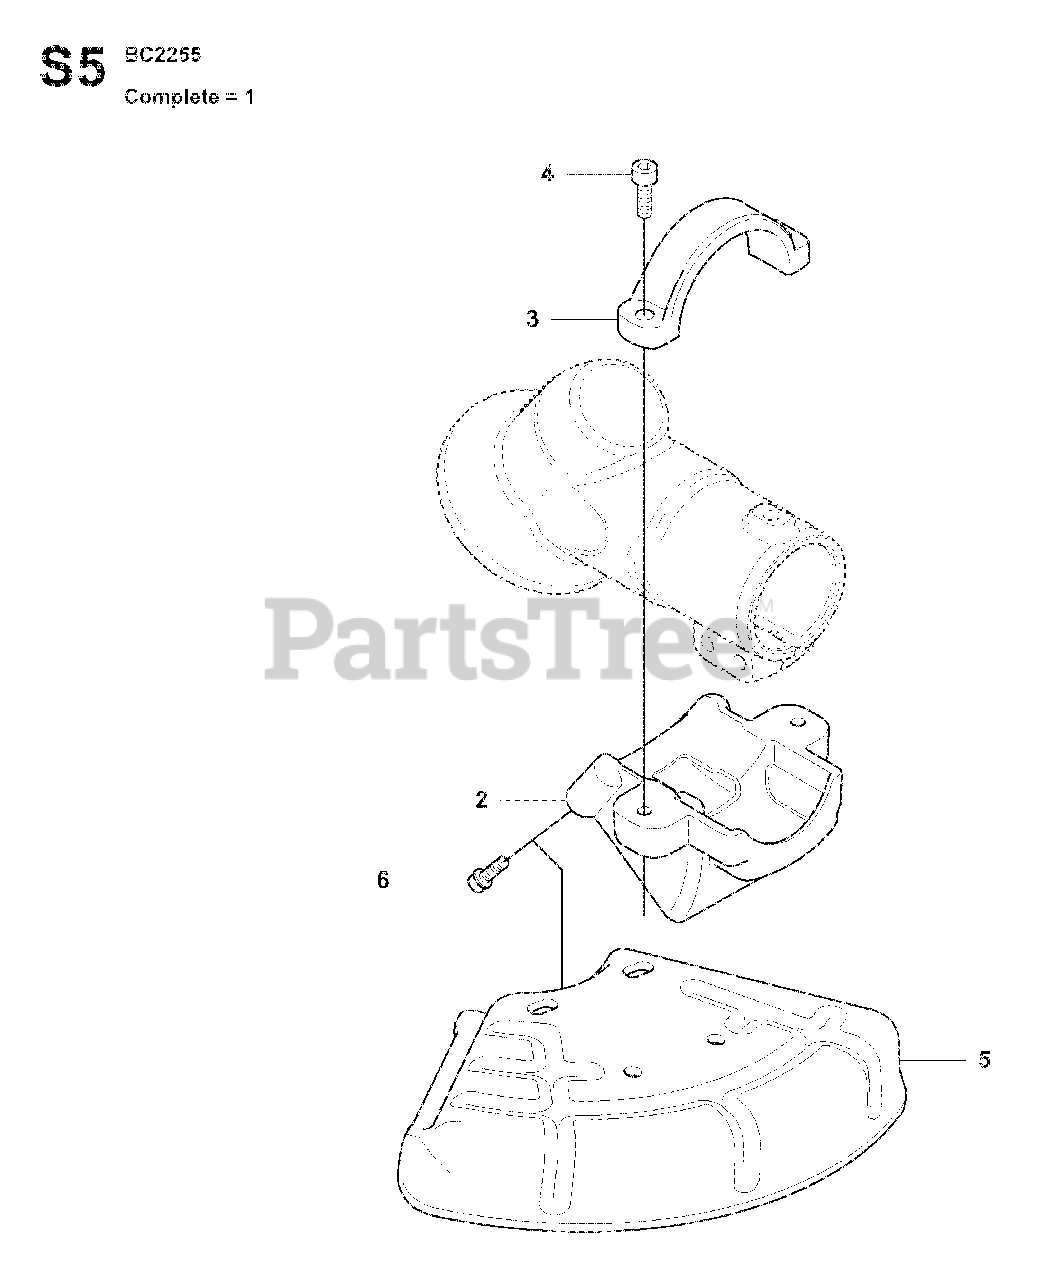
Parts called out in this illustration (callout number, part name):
2	BLADE GUARD SAW
5	BLADE GUARD SAW
6	SCREW IHSCFM
